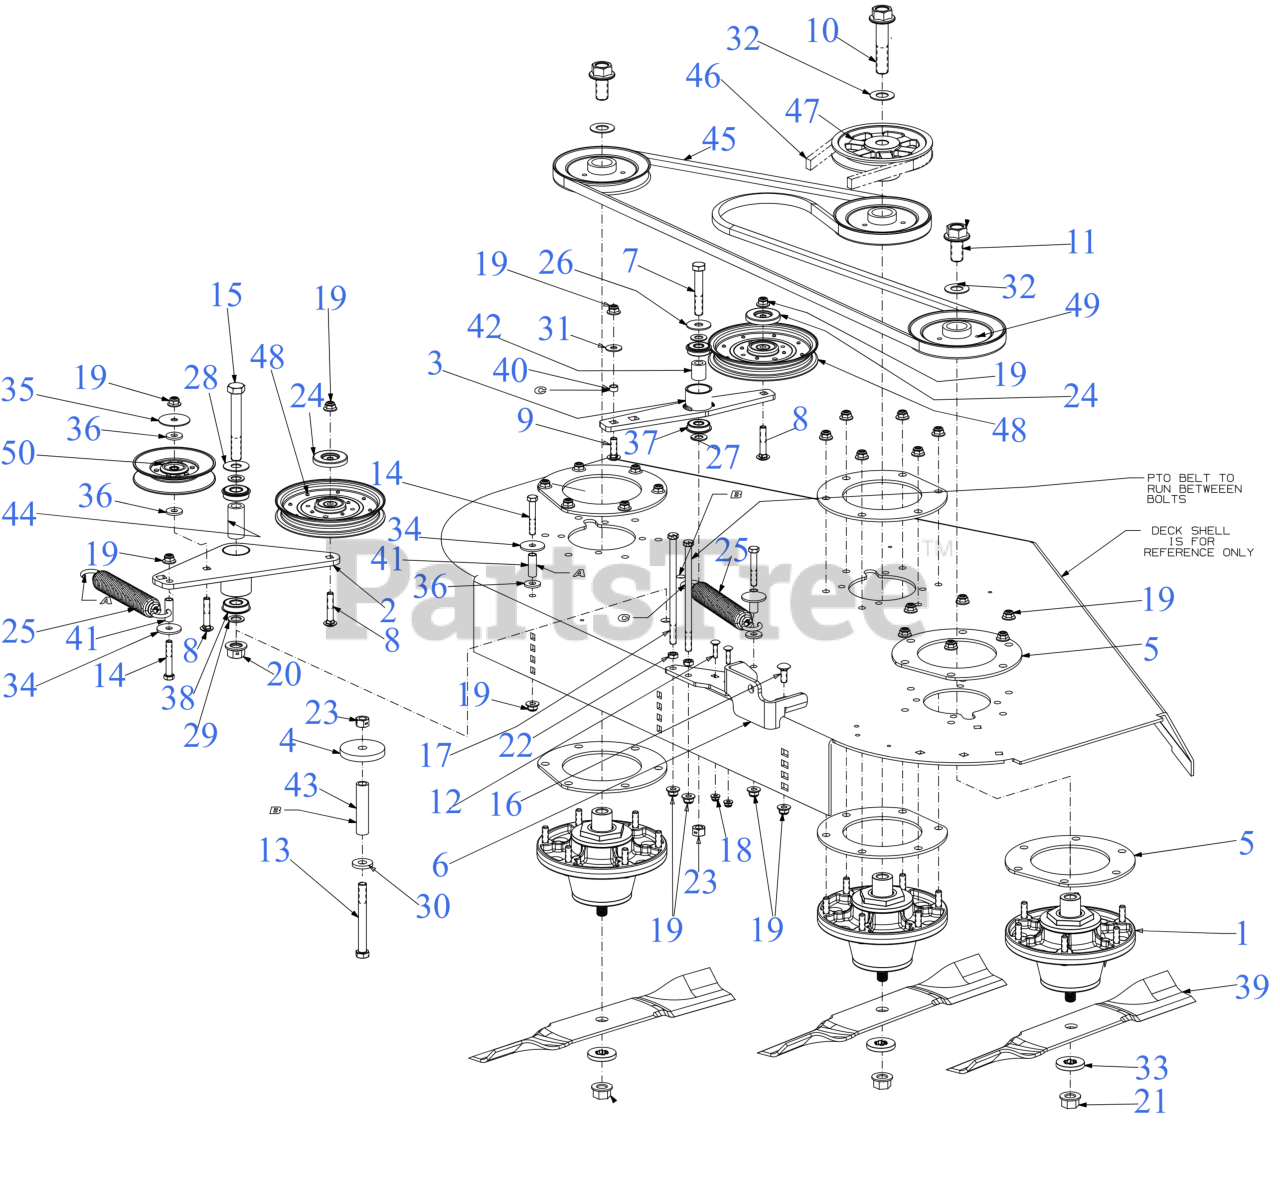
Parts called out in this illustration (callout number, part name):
1	SPINDLE ASSEMBLY
3	IDLER BRACKET
4	SPACER PLATE
5	SPINDLE SUPPORT BRACKET TOP/BTM
6	DECK STABILIZER BRACKET
7	SCREW-HEX 1/2-13 x 3.00
8	CARRIAGE BOLT 3/8-16 x 2
9	CARRIAGE BOLT 3/8-16 X1.25 GR5
10	CAP SCREW-HHFLG 3/4-10 X 3.50 GR8
11	CAP SCREW-HHFLG 3/4-10 X 1.50 GR8
12	SCREW 1/4-20 x 1 GR5
13	SCREW 1/2-13 x 4.5 GR 5
14	SCREW 3/8-16 x 2.25 GR5
15	SCREW 5/8-18X4.5 GR5
16	CARRIAGE BOLT 3/8-16 x 1.00 GR5
17	SCREW 3/8-16 x 7.00 GR5
18	FLANGE LOCK NUT
21	FLANGE NUT - 5/8-18 GDE 8
23	HEX NUT CTR LK 1/2-13
24	PULLEY CAP
25	SPRING 1.25" DIA x 8.5" LONG
26	WASHER .51 x 1.5 x .07
27	FLAT WASHER .510 x .995
28	FLAT WASHER-.63IDX1.595ODX.62
29	FLAT WASHER
30	FLAT WASHER .531 x 1.25 x .181
31	WASHER-.395 x 1.0 x .62
32	FLAT WASHER
33	FLAT WASHER - SPECIAL
34	FLAT WASHER .406X1.500X.105
35	HUB CAP WASHER .406 x 1.92 x .060
36	FLAT WASHER .406ID X1.0 OD
37	ROLLER BEARING .5X1.37X.44
38	BALL BEARING W/RET
39	19" BLADE (HI LIFT)
39	Cub Cadet 54" HI LIFT BLADE SET
39	LOW-LIFT 19"BLADE (54"DECK)
39	BLADE- HI LIFT 19.0 XTREME
39	BLADE-19"MULCH 54"
39	19" XTREME BLADE
42	SPACER 0.51 x 0.88 x 1.00
44	SPACER 0.63 x 1.00 x 2.01
45	BELT-B SECTION 119.45"
46	V-BELT B SEC x 101.1
47	PULLEY-6.96 OD x .750 ID
48	IDLER PULLEY
49	SPINDLE PULLEY 6"
50	IDLER PULLEY 5.06 OD
